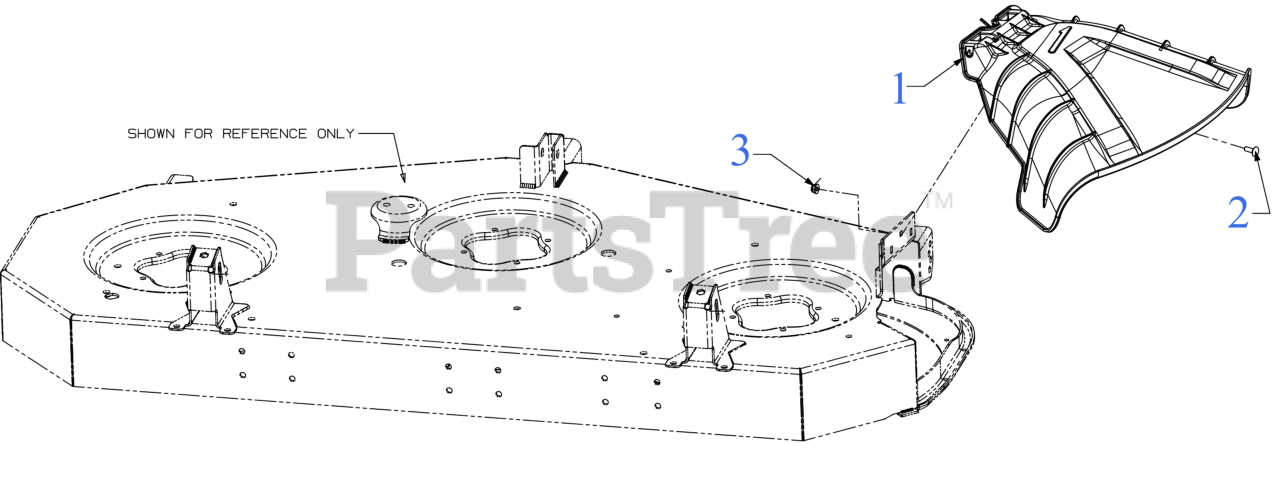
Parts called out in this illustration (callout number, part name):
1	50/54" CHUTE ASSEMBLY
2	SCREW 1/4-20 x .75 GR5
3	FLANGE LOCK NUT
